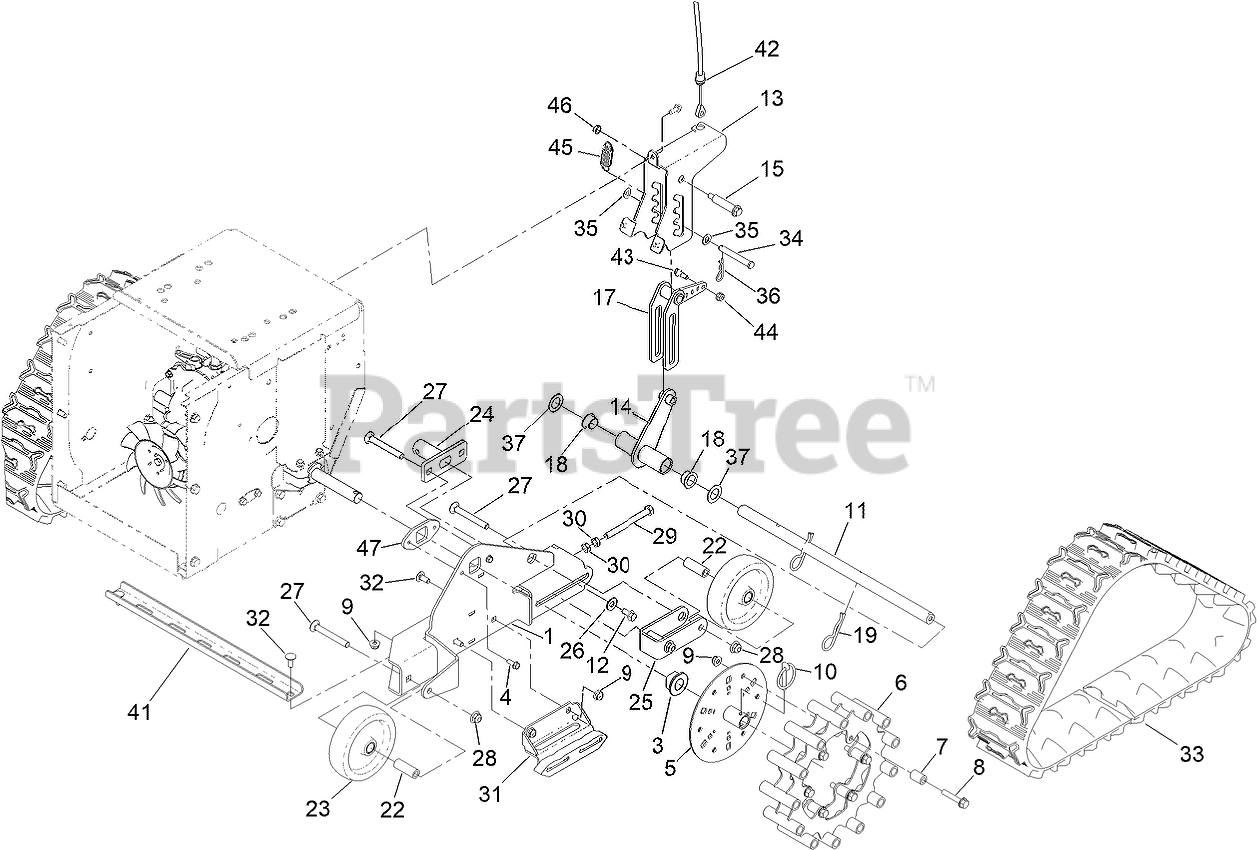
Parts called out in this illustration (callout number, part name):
1	SUPPORT-TRACK, ASM LH
3	BUSHING-AXLE
4	SCREW-HWH
5	HUB-DRIVE, WELD ASM
6	WHEEL-DRIVE, WELD ASM
7	TUBE-SUPPORT
8	SCREW-HHF
9	NUT-HF
10	KLIK PIN ASM
11	BAR-PIVOT
12	SCREW-HHF
13	BRACKET-HEIGHT, ADJUSTER
14	PIVOT-LINK, WELD ASM
15	BOLT-SHOULDER
17	LATCH ASM, WELDED
18	BUSHING-FLANGE
19	PIN-HAIR
22	BUSHING-TENSIONER
23	WHEEL-BOGEY
24	TENSIONER, WELDED
25	YOKE-BOGEY
26	WASHER-FLAT
27	BOLT-CARRIAGE
28	NUT-HF, NI
29	SCREW-HH
30	WASHER-FLAT
31	SKID-TRACK, ASM
32	BOLT-CARR
33	TRACK-SNOW
34	PIN-CLEVIS
35	WASHER-THRUST
36	PIN-HAIR
37	WASHER-THRUST
41	BRACE-FRONT
42	CABLE-ADJUST, HEIGHT
43	BOLT-SHOULDER
44	NUT-FLANGE, NI
45	SPRING-EXTENSION
46	NUT-HEX
47	SUPPORT-BUSHING, AXLE
